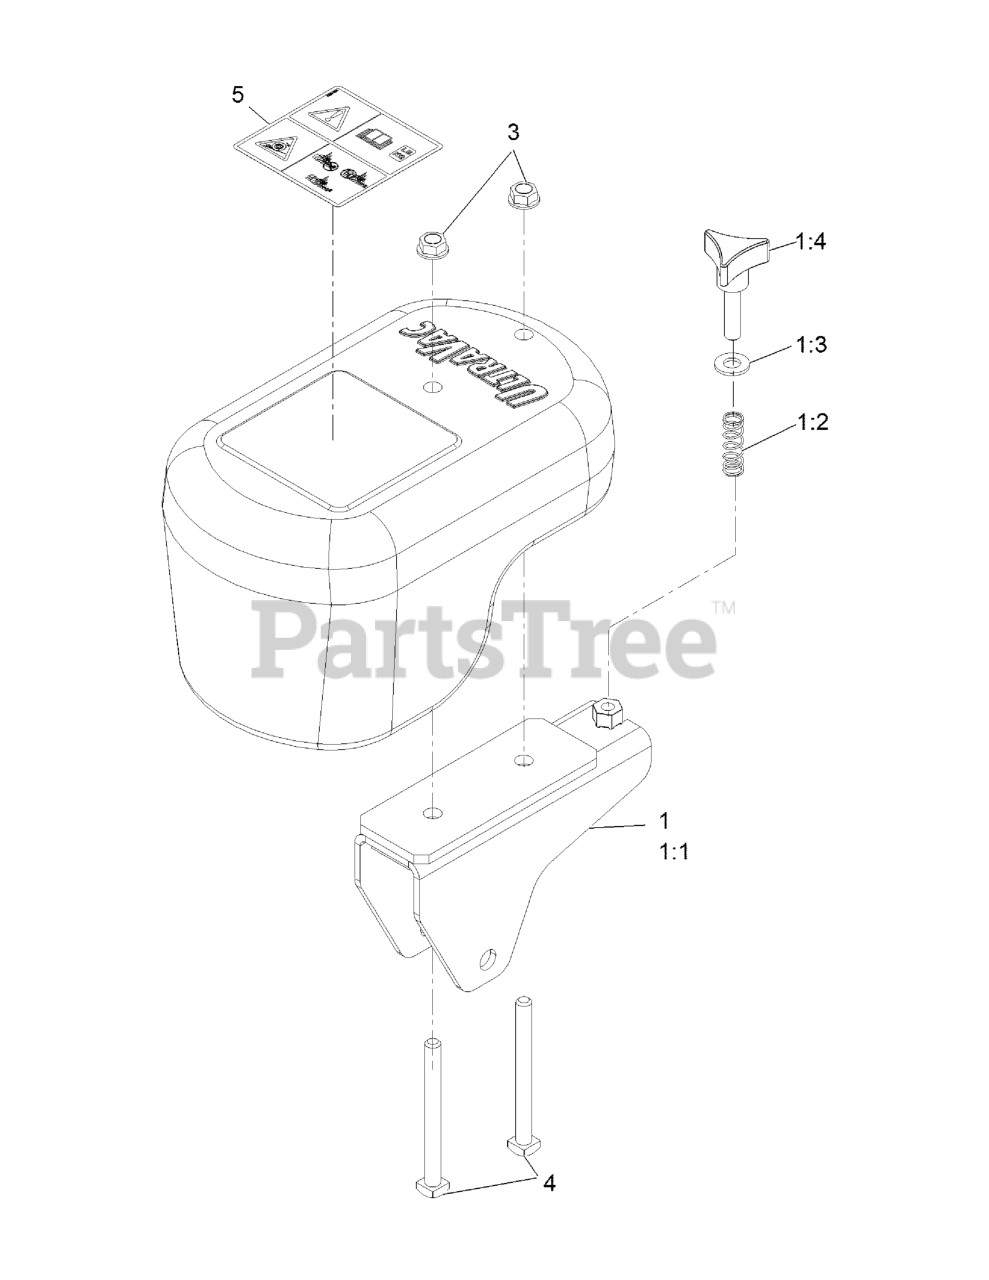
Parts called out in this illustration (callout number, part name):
1	ASM,CASTER WEIGHT BRACKET
1:1	WLD,CASTER WEIGHT BRACKET
1:3	WASHER-FLAT
3	NUT-HHF, WHIZ
4	BOLT, SQUARE HEAD YZ
5	DECAL-WARNING, TRACTION
